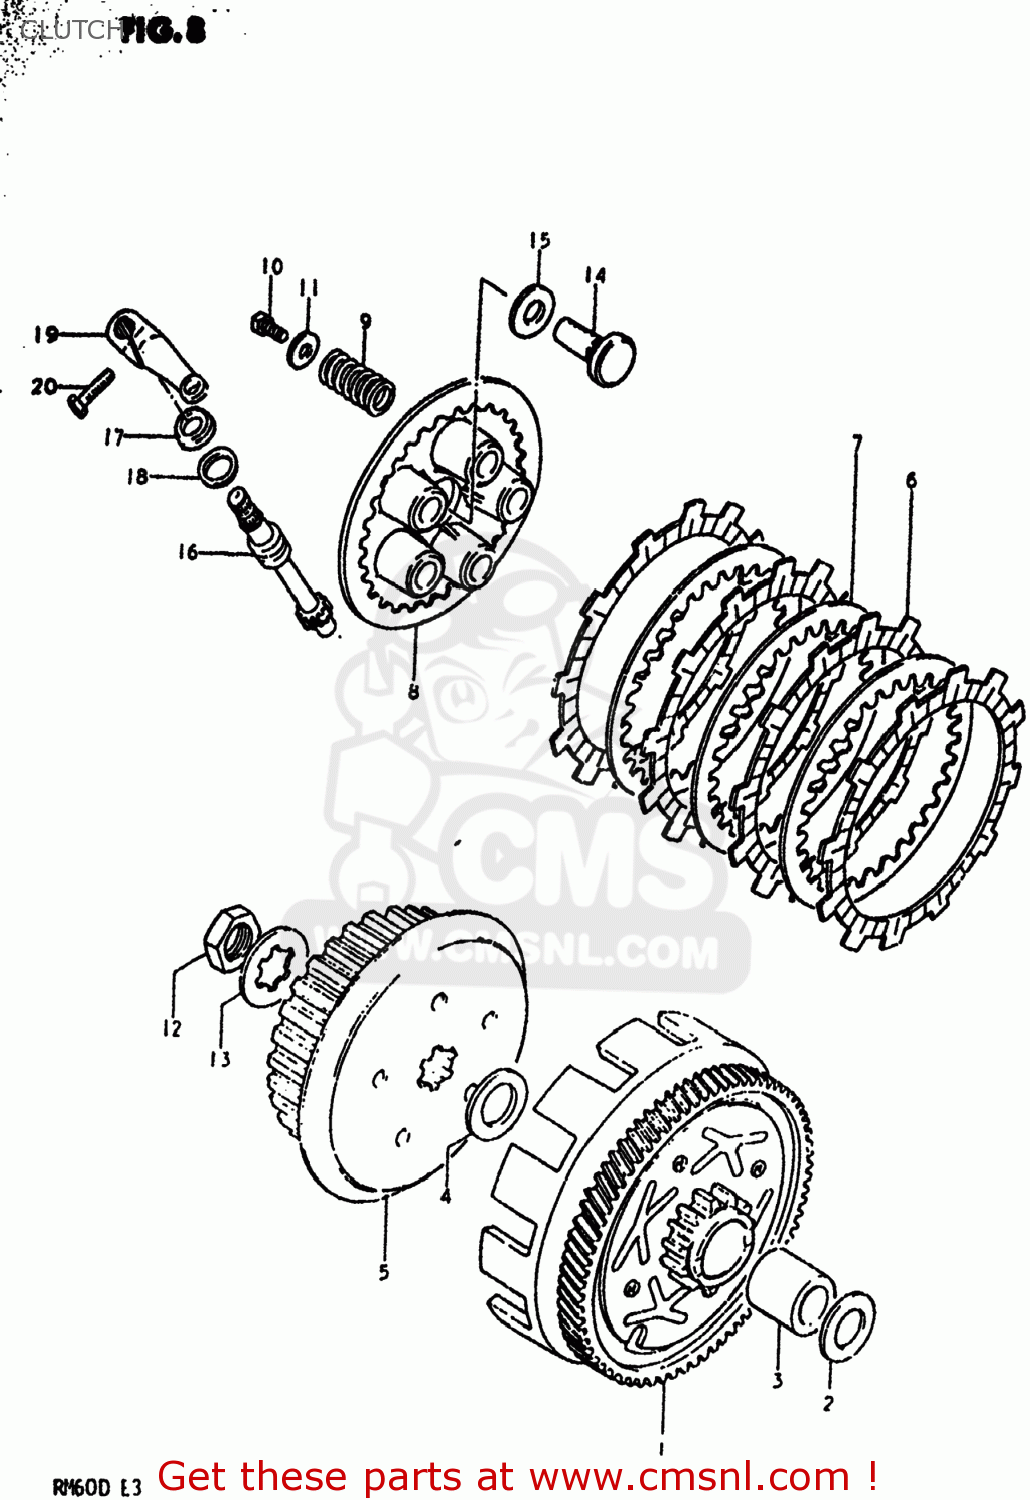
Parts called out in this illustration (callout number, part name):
1	GEAR ASSEMBLY,PRIMARY DRIVE
2	WASHER,THRUST
3	SPACER(17X22X28.5)
4	WASHER
5	HUB,CLUTCH SLEEVE
6	PLATE,CLUTCH DRIVE
7	PLATE,CLUTCH DRIVEN (NAS)
8	DISC,CLUTCH PRESSURE
9	SPRING
10	BOLT(5X16)
11	WASHER (5.5X16X1.2)
12	NUT
13	WASHER,LOCK
14	RACK,CLUTCH RELEASE
15	BEARING(10X22X2.8)
16	PINION,CLUTCH RELEASE
17	OIL SEAL
18	WASHER (12X17X1)
19	ARM,CLUTCH RELEASE
20	BOLT, UPPER
